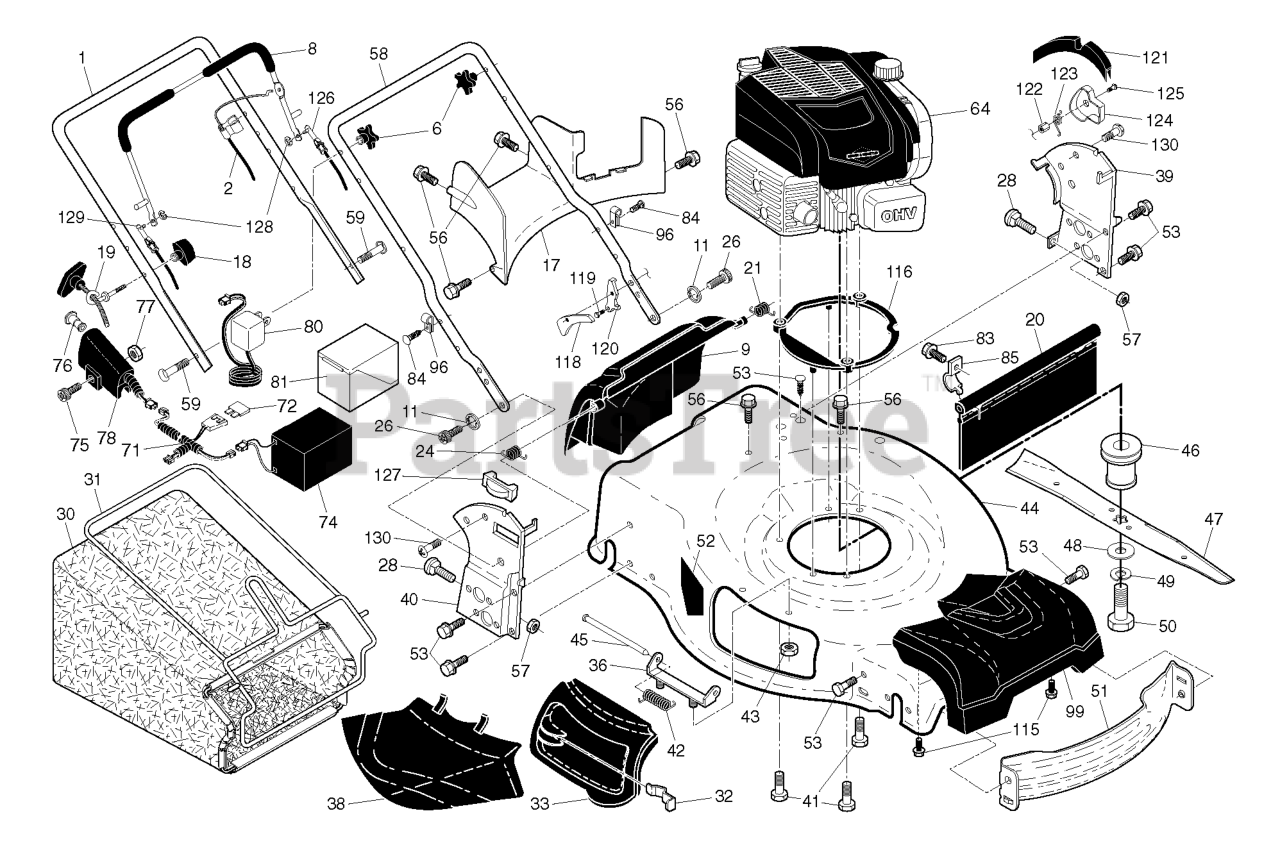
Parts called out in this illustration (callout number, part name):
1	HANDLE.UPPER.3.POS.BS.AW2.GREY
2	CABLE.MZR.RGD.22.B&S/HON.ERGO
6	KNOB.HANDLE.PLASTIC.STAR.BLACK
8	BAIL.CONTROL.MZR.ERGO.EZS.O/B
9	DOOR.REAR.ASM.22+GEN.FG/RG.498
11	E-RING.12MM.SHAFT
17	BAFFLE.REAR.22+RGD.AWD.PLASTIC
18	T-KNOB.NEW ROPE GUIDE
19	GUIDE.ROPE.BLK.ZINC.CHROM
20	SKIRT.REAR.22PLUS.RGD.LW(2 2MC
21	SPRING.LH.BLACK
24	SPRING.RH.GRAY
26	SCREW,DOOR/HANDLE.PIVOT
28	BOLT.CARRIAGE.LN.5/16-18X.5/8
30	GBAG.B561029EM.GRY/SILV
31	FRAME.GBAG.22+.BLK
32	LATCH.DOOR.ZINC
33	DOOR.MULCH.22 PLUS.HUSQ.GREY
36	BRACKET.ASM.HINGE.21.FWGD.
38	DEFLECTOR.CLIPPING.22.BLACK
39	BRACKET.ASM.HANDLE.LT.22+.498
40	BRACKET.ASM.HANDLE.RT.22+.498
42	SPRING.TORSION
43	NUT.FLANGE.1-4-20-SERR
44	KIT.HSG.22+AWD.MC.WO.668.TRI
45	ROD.HINGE.21
46	ADAPTER BLADE, 25 MM 22+, AWD,
47	BLADE.22.MULCH.STANDARD
48	WASHER,HARDEN
49	LOCKWASHER
50	BOLT.BLADE
51	BAFFLE.FRONT.22.PLUS
52	DECAL.INTERNATIONL.CUTFINGER
53	BOLT.5/16HEX.WHS.HD
56	SCREW.HX.13X.750
57	NUT.FLANGE.5/16
58	HANDLE.LOWER.22+EZS.498
59	BOLT, HANDLE 5/16-18X1.75
71	HARNESS.WIRE.ES.RGD.BUTTON.CON
74	BATTERY.12V.22+RWGD
75	BOLT.M6-1X40.T30
76	BUTTON.KEY.CYLINDER.BLACK
77	NUT.M6-1 NYLOC
78	STARTER.ASM.PUSH.BUTTON
80	CHARGER.BATT.12V LEAD-ACID.DOM
81	COVER.BATTERY.BOX 22+RDG.GRY
83	TAPPING SCREW
84	FASTENER.PUSH.O.250X0.783
85	BRACKET.SKIRT.22+.BZP
96	CLIP.CABLE.BLK
99	COVER.ASSEMBLY.FRONT.22+AWD
115	SCREW.SHOULDER.5/16X1.375
116	SPACER.AWD.B&S
118	COVER.INSIDE.LOWER.LT.EZS
119	BOLT.PAWL.M6
120	PAWL.ADJUSTMENT.EZS.LEFT
121	BRACKET.BAG.ASM.EZS.LH.BLK
122	NUT.PAWL.M6
123	SPRING.TORSION.PAWL ENG.LT
124	COVER.OUTSIDE.LOWER.EZS.LT
125	SCREW.TORX.PAN HEAD.M6-1
126	CABLE.MZR.EZS.LH.DSTR/ERGO
127	DOOR.REAR.LIFT.ASM EZS
128	E-RING.5/32.HD
129	CABLE.MZR.EZS.RH.ERGO.PB
130	SCREW.PAN.HEAD.#10
